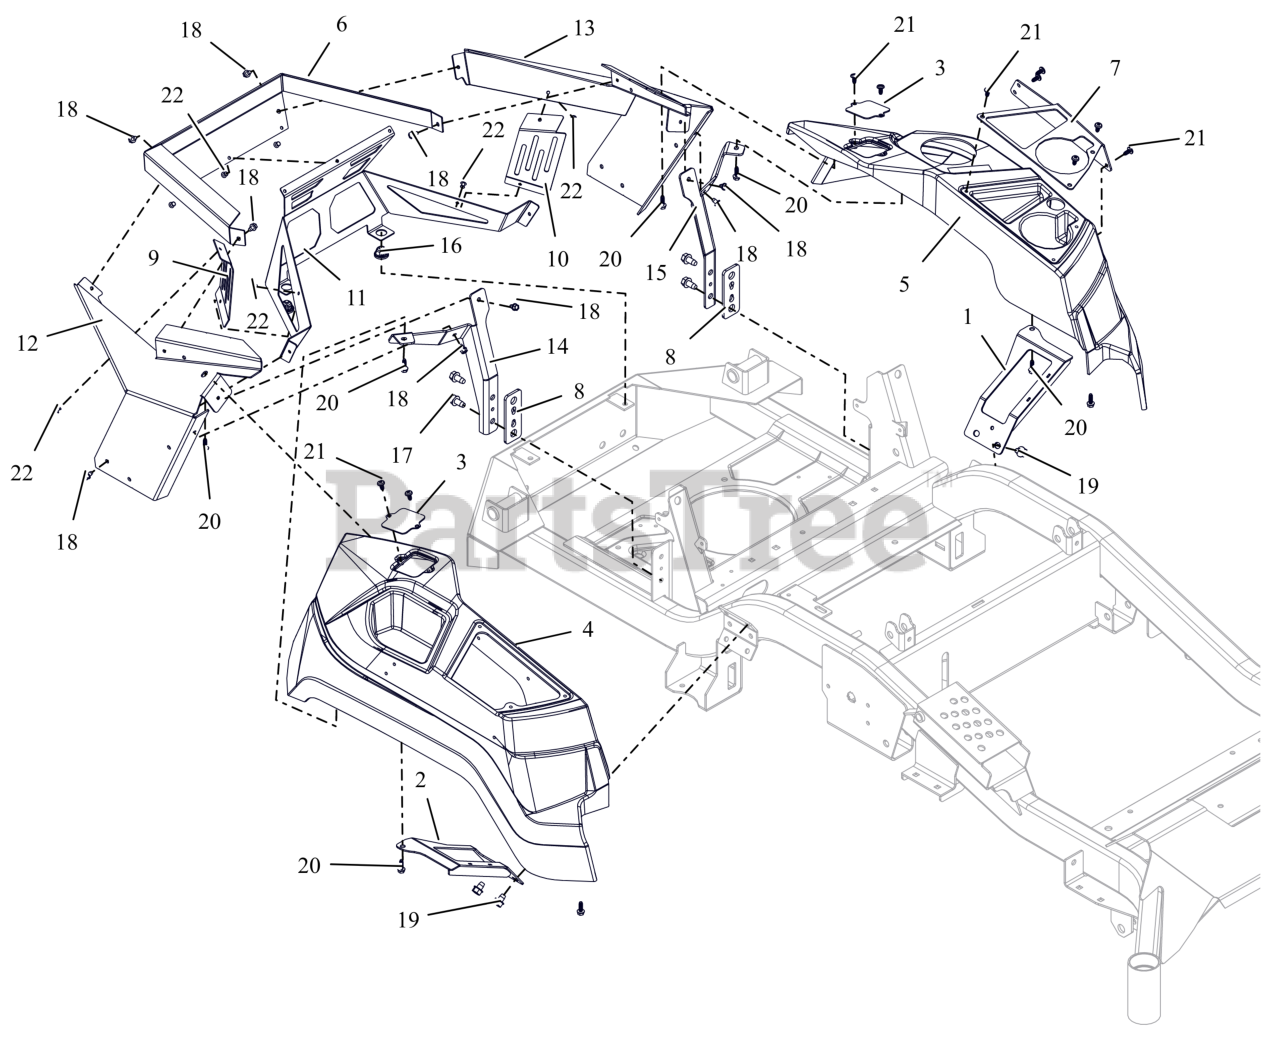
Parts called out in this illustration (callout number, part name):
1	WLDMT, LH FENDER MOUNT
2	WLDMT, RH FENDER MOUNT
3	PLATE, ROPS HOLE-HD
4	FENDER, RH APEX - 2017
5	FENDER, LH APEX
6	GUARD,ENGINE WRAP
7	PLATE, APEX CUP HOLDER COVER
8	PLATE, CONTROL PANEL SPACER
9	SHIELD,RH ENGINE GUARD VALVE
10	SHIELD,LH ENGINE GUARD VALVE
11	GUARD, ENGINE
12	PANEL, RH REAR FENDER MOUNT
13	PANEL, LH REAR FENDER MOUNT
14	BRKT, RH FENDER MTG (ORANGE)
15	BRKT, LH FENDER MOUNT (ORANGE)
16	GROMMET, 10MM BOLLHOFF
17	SCR,TAP .375-16X.75 HWH TR ZCC
18	SCR,TAP .25-20X.375 HWH TR ZCC
19	SCR,TAP .375-16X.50 HWH TR ZCC
20	SCR, PLASTITE .25-10X.75 ZCC
21	SCR-PAN .25-15X.50 6L H/LZB500
22	RIVET, .1875 AL/AL .126-.250
